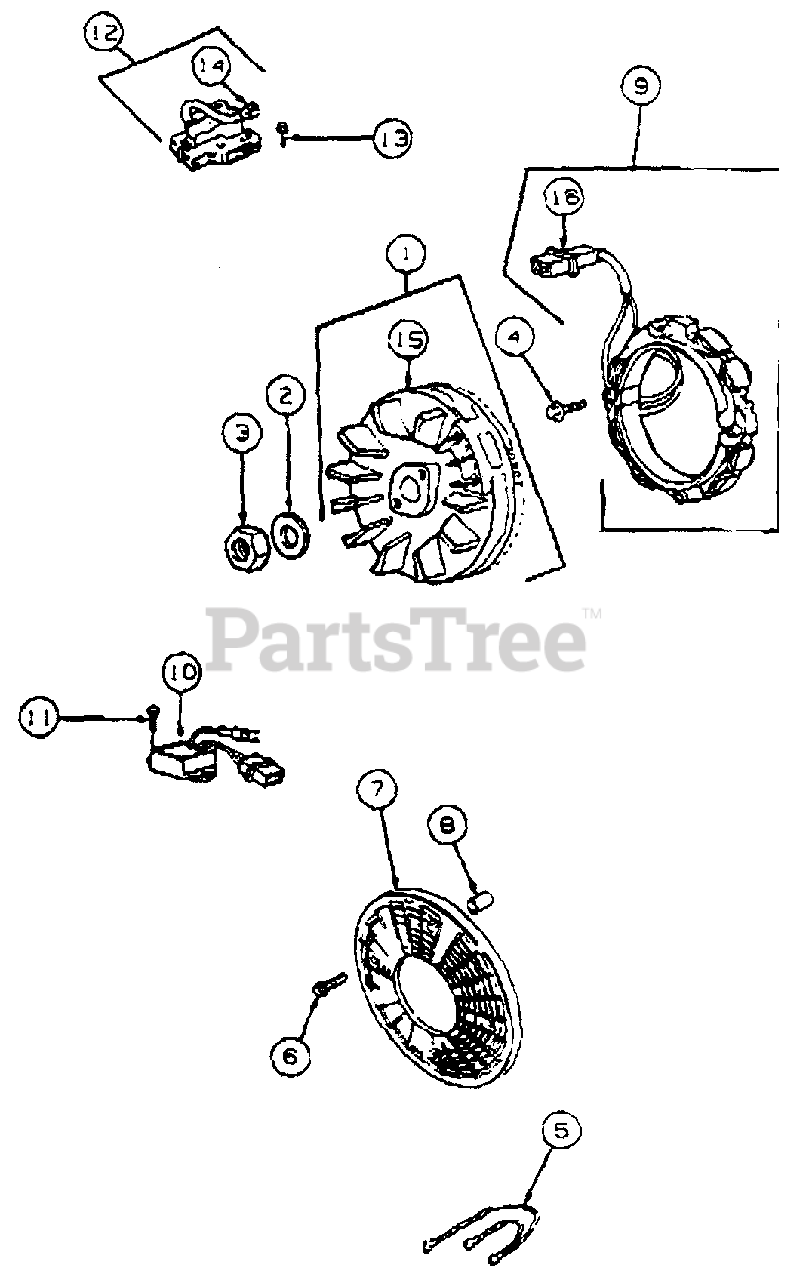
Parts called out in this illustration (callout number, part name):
1	Flywheel & Ring Gear
2	Washer, Spring
4	Screw, Mounting
5	Wire, Ground
6	Screw, Sems
7	Screen, Rotating
8	Spacer
9	Stator, 16 Amp
10	Regulator
11	Screw, Mounting
12	Armature
13	Screw, Mounting
14	Terminal
15	Gear, Flywheel Ring
16	Diode & Connector Assy
